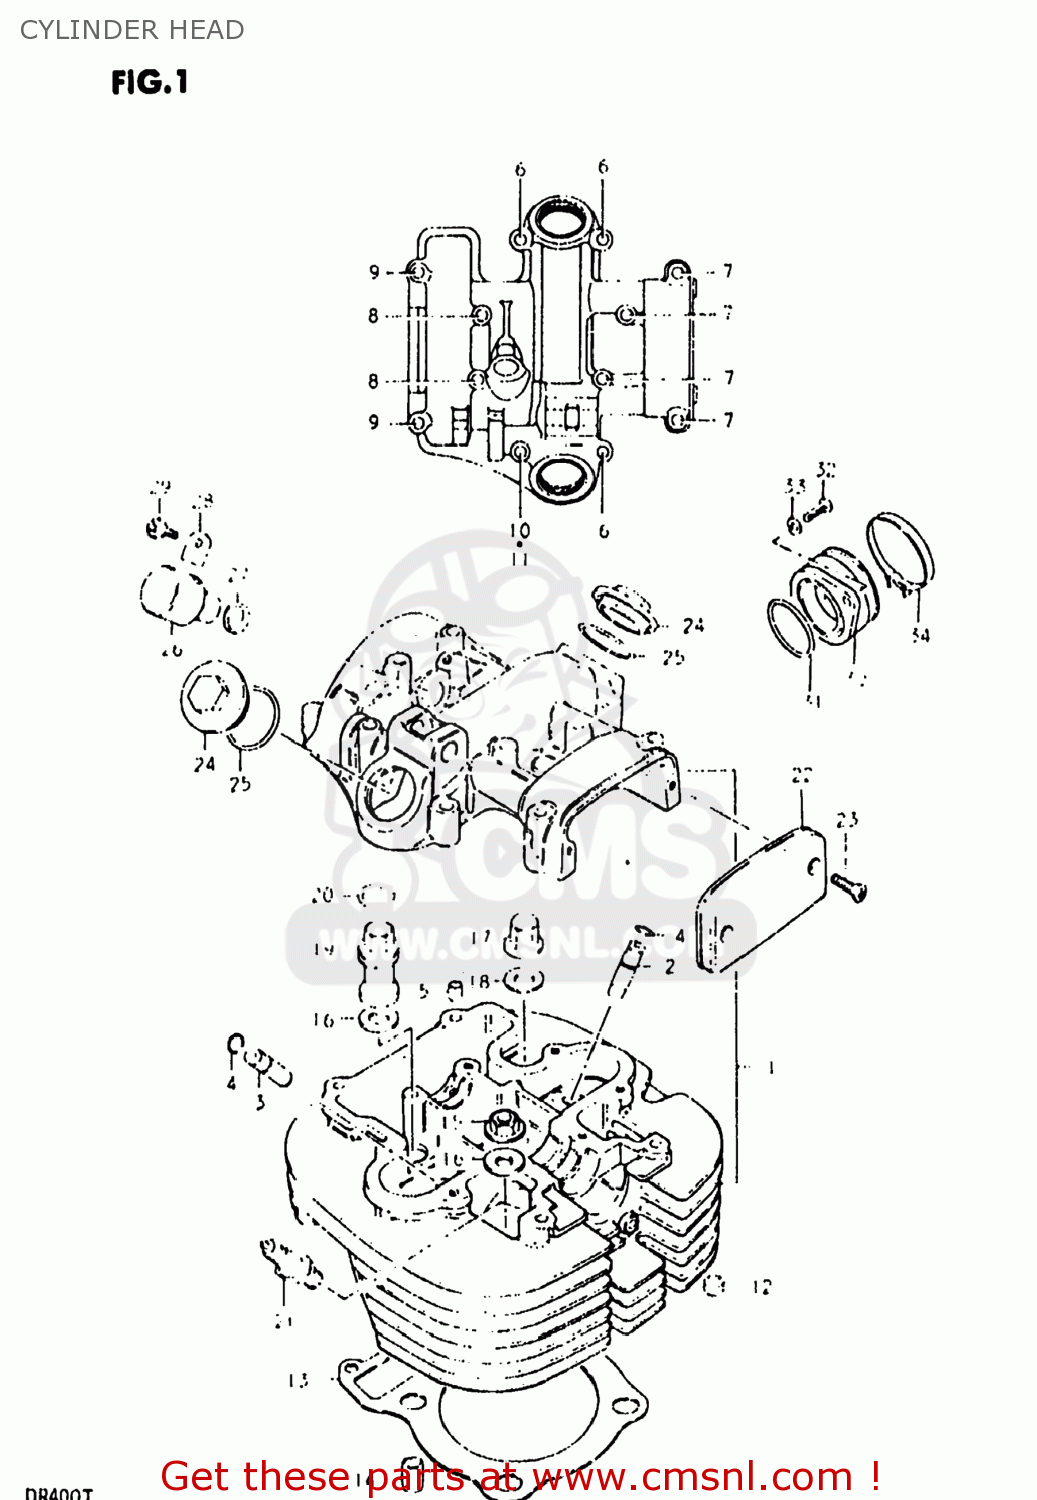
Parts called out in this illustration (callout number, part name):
1	HEAD ASSEMBLY,CYLINDER
2	GUIDE,INTAKE VALVE
3	GUIDE,EXHAUST VALVE
4	RING,SNAP
5	PIN(6.2X8X11)
6	BOLT 6X35
7	BOLT ,6X50
8	BOLT 6X65
9	BOLT(6X125)
10	BOLT
11	GASKET (NAS)
12	PAD,CYLINDER
13	GASKET,CYLINDER HEAD (NAS)
14	PIN
15	NUT
16	WASHER(10.5X22X2.3)
17	NUT
18	GASKET(10.5X22X2) (NAS)
19	NUT,CYLINDER HEAD SEAL
20	O RING(D:2.4,ID:17.8)
21	SPARK PLUG D8EA
22	CAP,CYLINDER HEAD COVER
23	SCREW
24	CAP,INSPECTION
25	O RING(D:3,ID:29.5)
26	PLUG
27	SEAL,TACHOMETER DRIVEN
28	PLATE,TACH DRIVE GEAR SLEEVE
29	SCREW(5X12)
30	PIPE,INTAKE
31	O-RING (D:2.4 ID:39.7)
32	SCREW
33	LOCK WASHER
34	CLAMP
